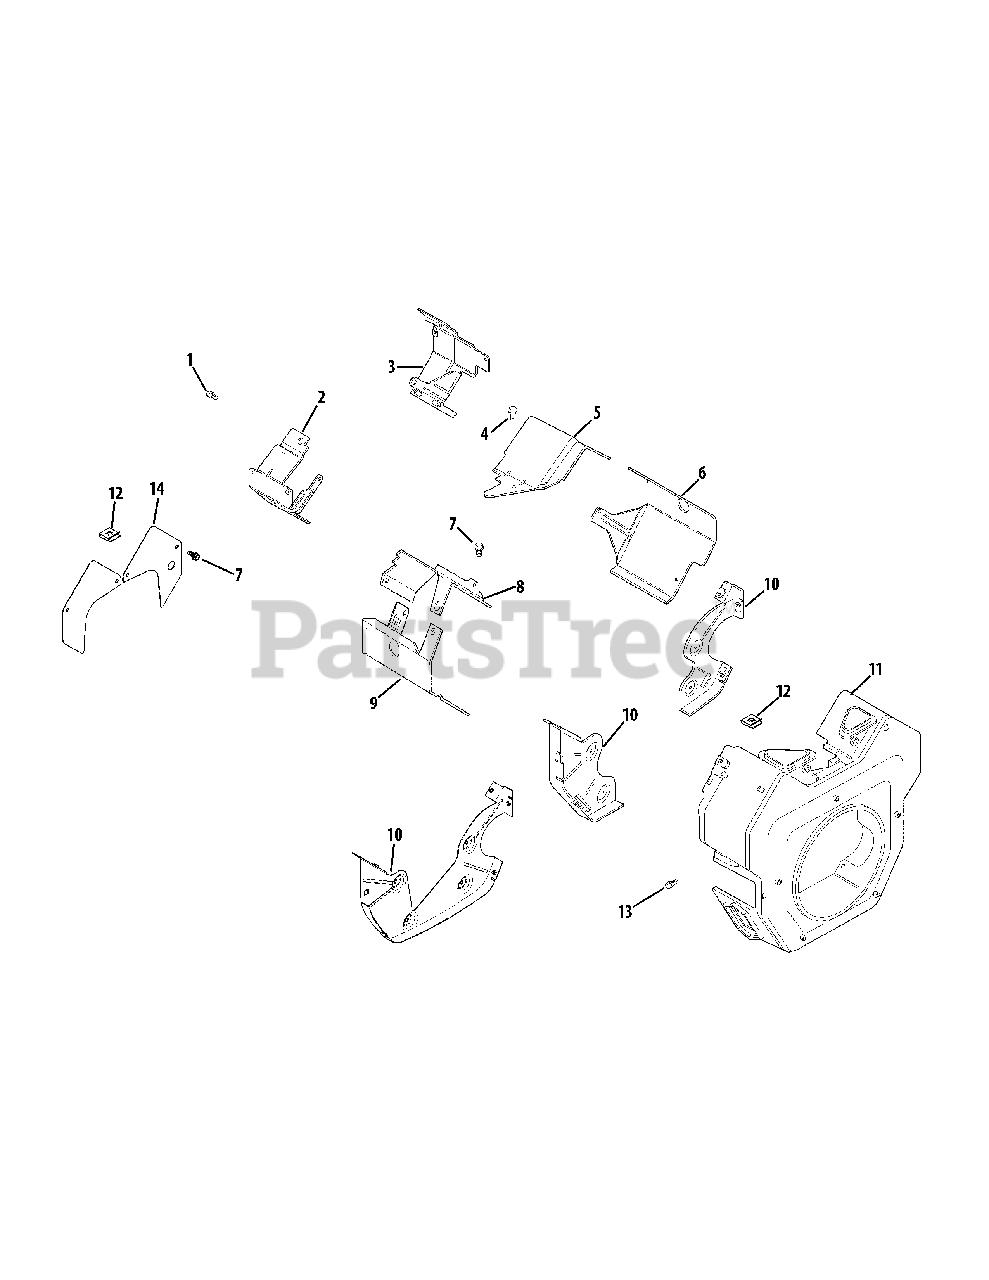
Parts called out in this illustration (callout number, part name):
1	Flange Screw, M6 x 1.0 x 10
2	Ducted Air-Oil Filter Baffle
3	Ducted Air-Starter Baffle
4	Thread Forming Screw
5	Valley Baffle, #1 Cylinder
6	Cylinder Baffle Kit, #1 Side
7	Thread Forming Screw
8	Valley Baffle, #2 Cylinder
9	Cylinder Baffle Kit, #2 Side
10	Backing Plate Kit
11	Blower Housing Assembly Kit
12	Baffle Mounting Clip
13	Thread Forming Screw
14	Access Panel Kit
